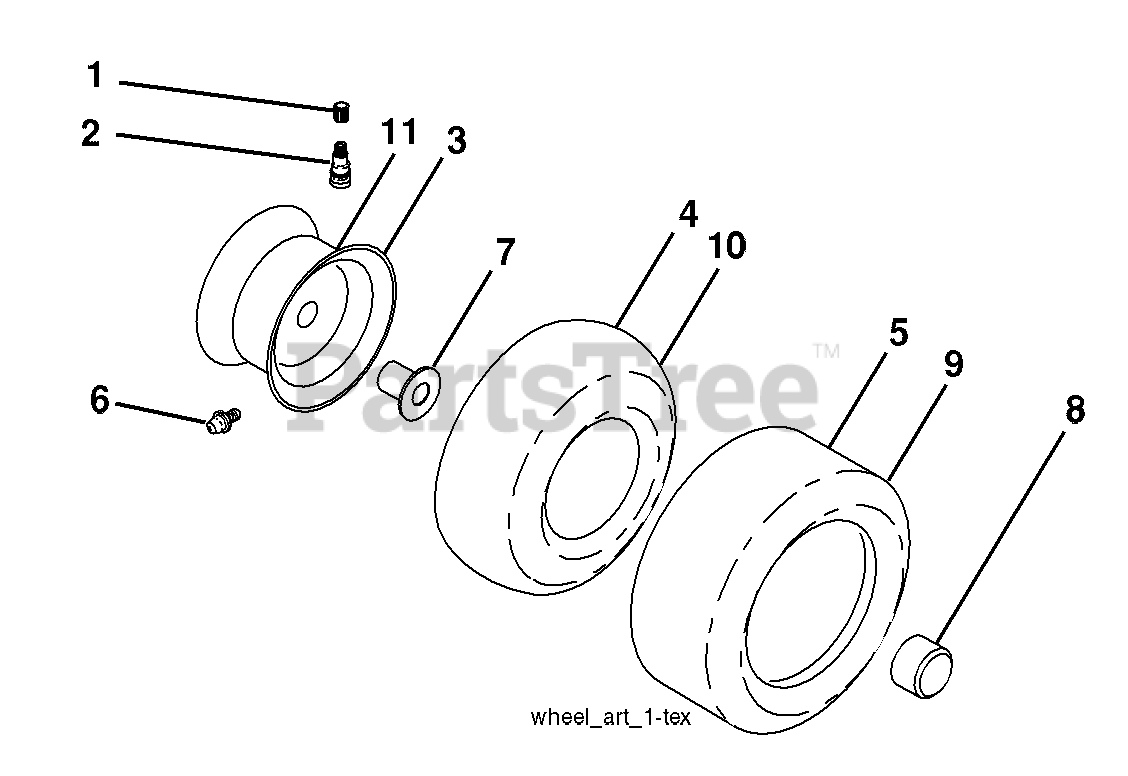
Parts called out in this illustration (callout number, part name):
1	Cap Valve Tire
2	Stem Valve
3	Rim Front Service
4	Tube Front
5	Tire Front 15 x 6.0-6 Service
6	Fitting Grease
7	Bearing Flange
8	Cap Axle Blk 1 50 x 1 00
9	Tire R T 18 x 9.5-8 Service
10	Tube Rear
11	Rim Asm 8" rear Service
11	Sealant, Tire
